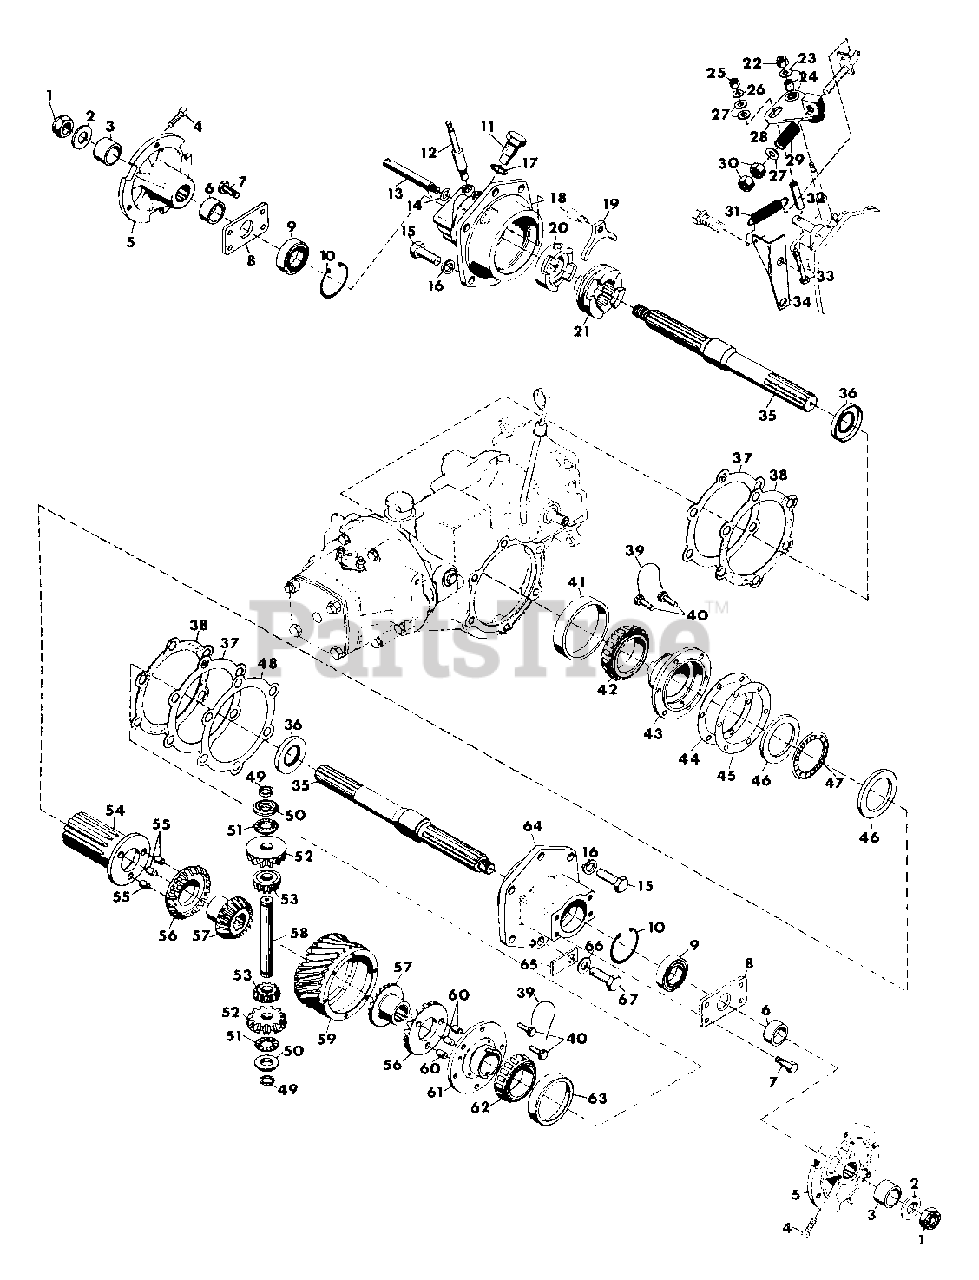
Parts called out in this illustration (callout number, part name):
1	Nut, Hex 3/4-10 Light Thin
2	Washer, Flat .812x1.469x.134
3	Spacer
4	Screw, Set 7/16-14x1.00 SQHCP
5	Hub, Wheel
6	Spacer
7	Bolt, Hex 3/8-16x.750
8	Plate, End
9	Bearing, Ball 1.000x2.000x.562
10	Ring, Retaining 2.000 Bore
11	Bolt, Stationary Clutch
12	Pivot, Stationary
13	Pin, Clutch Sliding
14	O-Ring .438x.625x.094
15	Bolt, Hex 1/2-13x1
16	Washer, Lock 1/2 Reg.
17	Washer, Oil Strainer Nut
18	Housing, Axle 2-Speed
19	Yoke, Shifting
20	Clutch, Stationary
21	Clutch, Shifting
22	Nut, Lock 5/16-18
23	Washer, Flat .344x.688x.065
24	Bushing, Nylon .375x.503x.875
25	Nut, Lock 1/4-20
26	Washer, Flat .281x.625x.065
27	Washer, Flat .406x.812x.065
28	Weldment, Arm Shifter
29	Spring, Compression 2x.720x15.5 Rate
30	Nut, Jam 3/8-24 Hex
31	Spring, Extension 2.50x.62
32	Bushing
33	Bolt, 1/4-20x2.25 Gr. 8 PHd
34	Bracket, Spring 2-Speed
35	Axle, Straight
36	Seal, Oil 1.188x2.000x.250
37	Shim, Axle Housing .020
38	Gasket, Axle Housing
40	Bolt, Special 5/16-18
41	Cup, Roller Bearing
42	Cone, Roller Bearing
43	Housing, Clutch
44	Shim, Clutch Worm Gear .020
45	Shim, Clutch Worm Gear .005
46	Race, Thrust 2.002x2.740x.031
47	Bearing, Needle Thrust .060
48	Shim, Axle Housing .005
49	Ring, Retaining .750 Shaft
50	Spacer, .765x1.245x.200
51	Bearing, Needle Thrust .752x1.240x.078
52	Gear, Differential Shifting Bevel
53	Gear, Spider Bevel
54	Shifter, Splined Pinned
55	Pin, Dowel .375x.375
56	Gear, Pinned Bevel
57	Gear, Differential Bevel
58	Pin, Spider
59	Gear, Worm 8 Start
60	Pin, Dowel .375x.500
61	Housing, Pinned
62	Cone, Roller Bearing
63	Cup, Roller Bearing
64	Housing, Axle
65	Washer, Oil Drain
66	Washer, Flat .531x1.062x.095
67	Bolt, Hex 1/2-13x1 Nylon Insert
